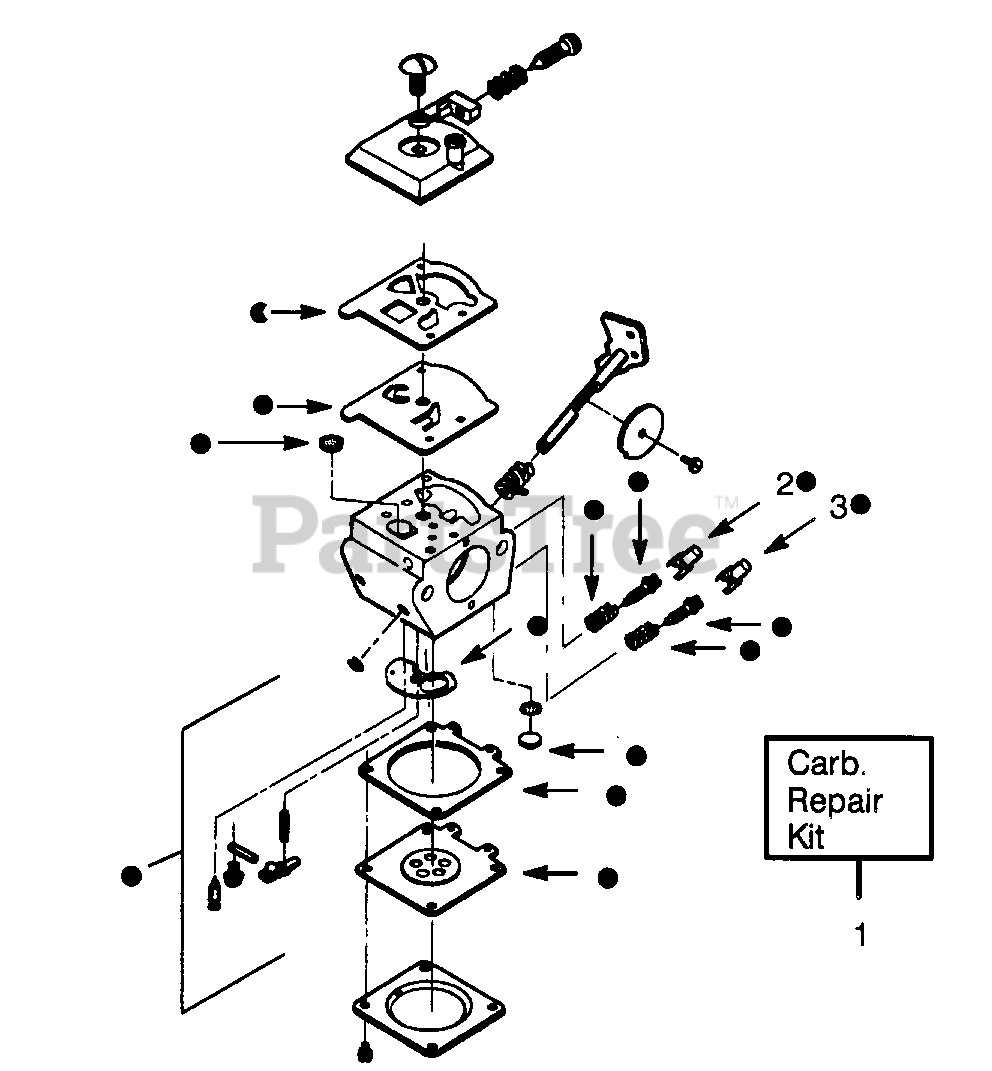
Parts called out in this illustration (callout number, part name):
1	WT-380
1	WT-299A
2	Limiter Cap-Low
3	Limiter Cap-High
